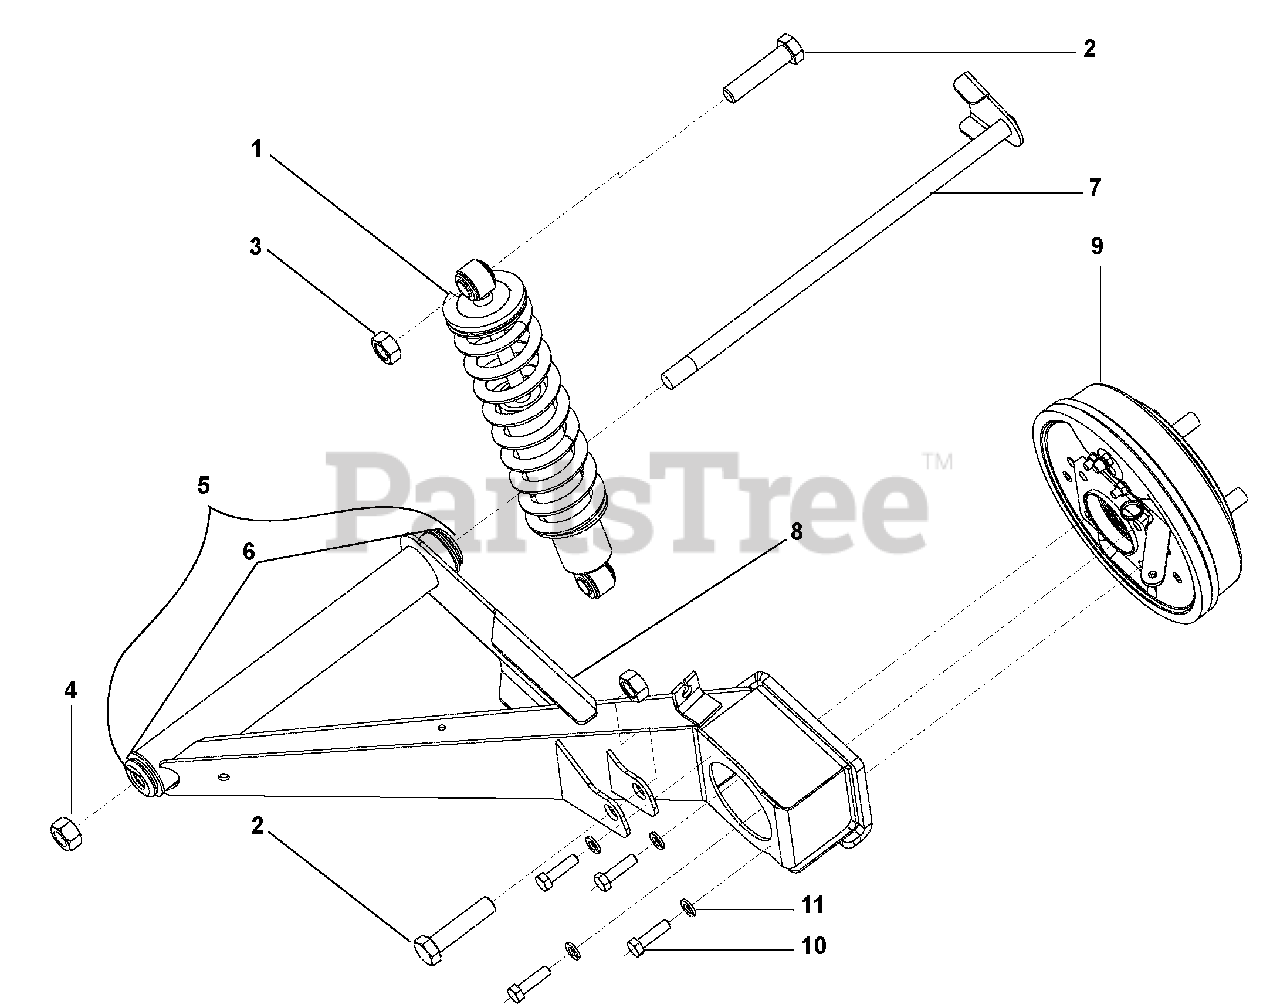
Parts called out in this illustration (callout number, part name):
1	SHOCK COIL REAR TRUCK
2	HHCS M14X2.00X60 GR8.8
3	NUT HEX NYLOCK M14X2.00
4	NUT HEX TOP LOCK 9/16-12 YLW
5	TRAILING ARM RH WELDMENT
6	BUSHING IDLER ARM RUBBER
7	CENTER PIVOT TUBE WELDMENT
8	TRAILING ARM PIVOT BOLT WELDMENT
9	RH DRUM ASM 18 OMM 4 ON 4" BC
10	HHCS M8 X 1.25 X 30 GR 10.9 YLW PLT
11	WASHER SPRING LOCK M8 PLT
